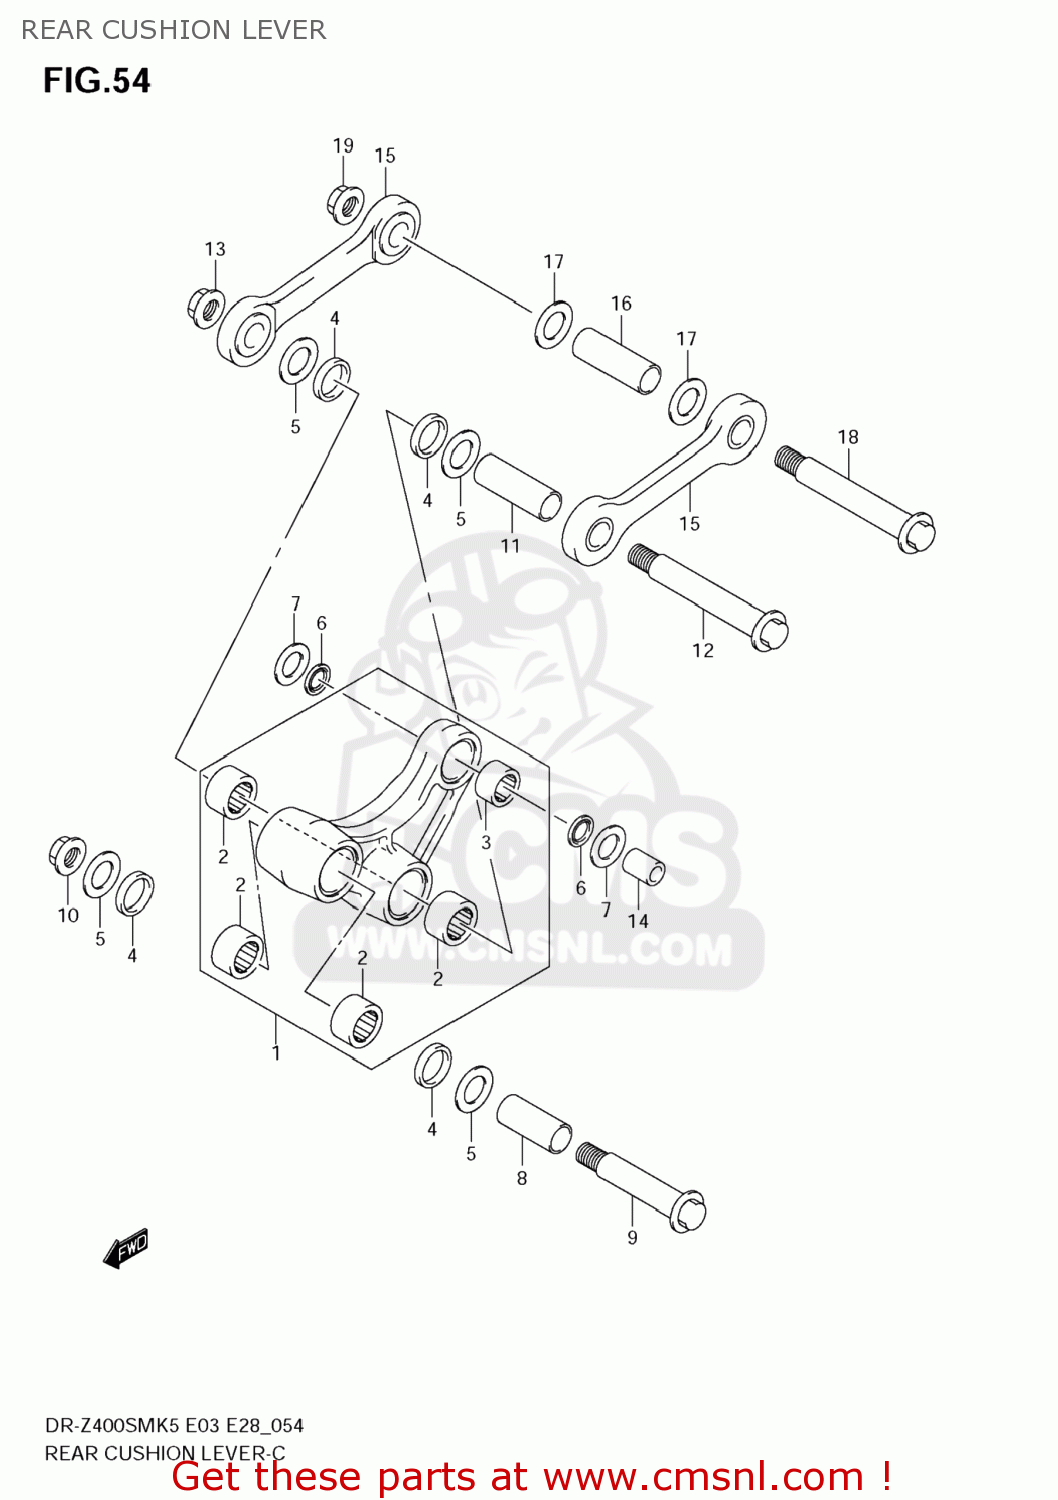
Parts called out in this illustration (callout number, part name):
1	LEVER SET,RR CUSHION
2	BEARING(20X27X15)
3	BEARING(16X22X12)
4	SEAL,CUSHION LEVER DUST
5	WASHER,THRUST SWINGARM RR
6	SEAL,OIL(16X22X2.5)
7	WASHER,THRUST LVR CUSHION RR
8	SPACER,CUSHION LEVER FR
9	BOLT,RR CUSHION LEVER FR
10	NUT
11	SPACER,RR CUSHION
12	BOLT,RR CUSHION
13	NUT
14	SPACER,RR CUSHION LEVER RR
15	ROD SET,RR CUSHION
16	SPACER,RR CUSHION
17	WASHER,THRUST SWINGARM RR
18	BOLT,RR CUSHION
19	NUT
